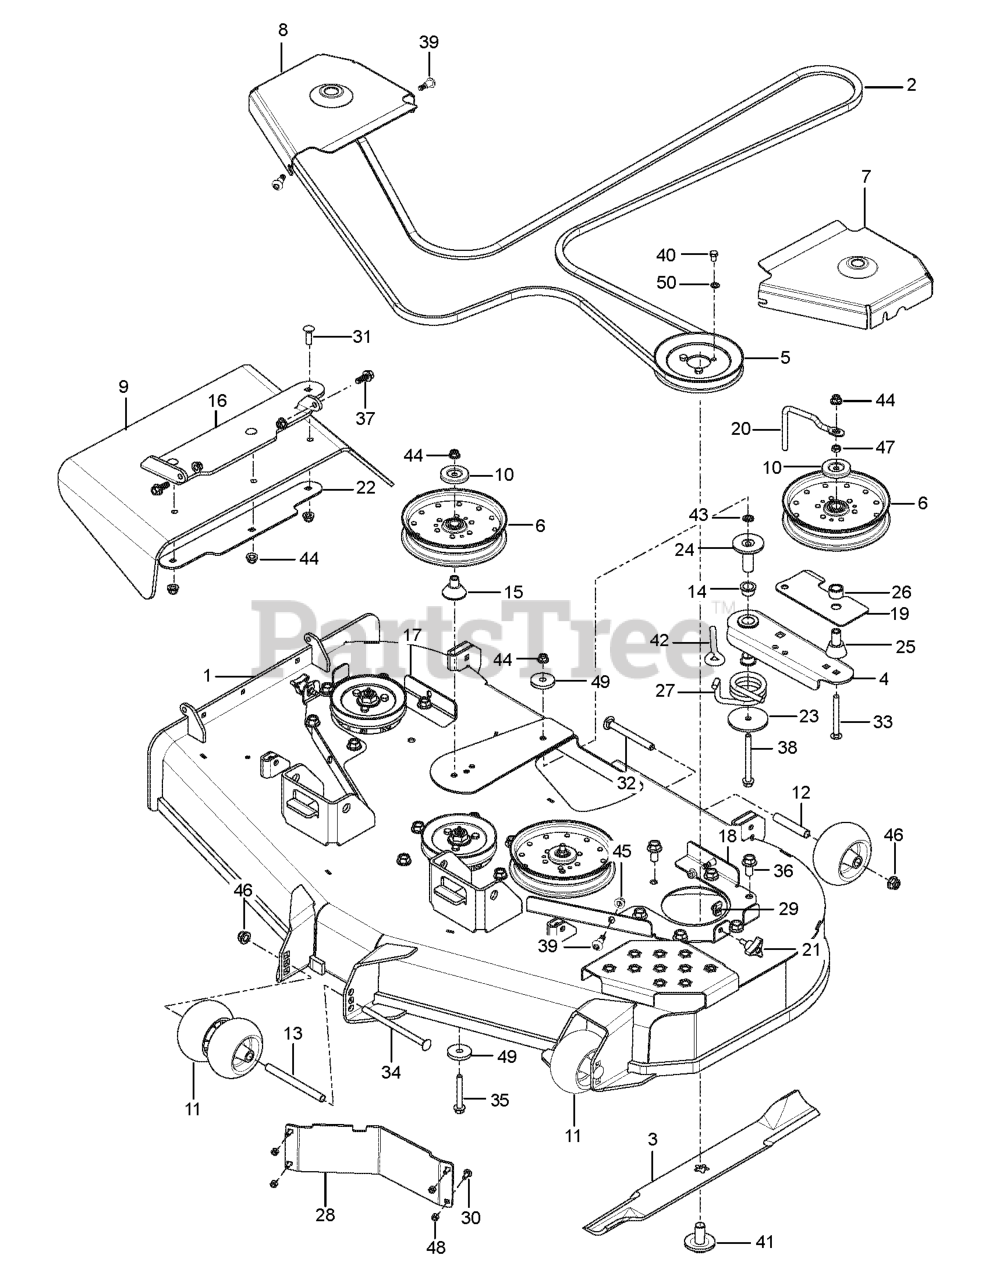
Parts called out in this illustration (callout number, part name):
1	DECK.SVC.W/DECALS.54".7GA.ORG
2	BELT.166".5V.SBR
3	BLADE, 19"
4	ARM.PNT.WLD.TENSIONR.IDLER.BLK
5	PULLEY - 5.93 OVER PINS
6	PULLEY - IDLER 7"
7	COVER.PULLEY.LH.PNT
8	COVER.PULLEY.RH.54"DECK.PNT
9	CHUTE.DISCHARGE
10	DUST SHIELD
11	ROLLER, GAUGE .635 BORN
12	TUBE, ROLLER AXLE
13	TUBE, ROLLER AXLE LONG
14	BEARING, FLANGE
15	BEARING, IDLER ARM
16	BRACKET.CHUTE.ORG
17	BRACKET.PULLEY.COVER.LH.PNT
18	BRACKET.PULLEY.COVER.RH.PNT
19	BELT.GUARD.LOWER.PLATE.PNT.431
20	KEEPER KEEPER., BELT
21	KNOB W/STUD
22	PLATE.BACKING.DISCHARGE.CHT.BK
23	PLATE.SPRING.RETAINER
24	SHAFT.MOUNT.ARM.IDLER
25	SPACER
26	SPACER.PULLEY.INTERMEDIATE
27	SPRING.TORSION.DECK.IDLER.TMSN
28	BAFFLE, DIVERTER 54"/60" LH
29	U-CLIP 5/16-18 NUT RETAINER
30	1/4-20X3/4 CARR BLT
31	BOLT.3/8-14X1.25
32	RHSNB 1/2-13 X 4.75 GR5 ZD
33	BOLT.RDHD SQNK 3/8-16 X 3-1/2
34	RHSNB 1/2-13 X 8 GR5 ZD
35	HHFS 3/8-16 X 2-3/4 GR5 ZD
36	HHFS 1/2-13 X 1 GR5 ZD
37	HHFS 3/8-16 X 1 GRD 5 ZD
38	HHFS 3/8-16 X 4 GR5 ZD
39	SCREW.SHLDR.3/8 X 1/2.5/16-18
40	HCS 5/16-18 X 1/2 GR 5 ZD
41	BLADE BOLT/WASHER
42	EYE BOLT, 3/8 X 4"
43	NUT 3/8 PALNUT RTNG BLK PHOS
44	NUT 3/8-16 HEX FLG NYLOC ZD
45	5/16-18 NYLOC FLANGE NUT
46	NUT, 1/2-13 HEX FLG NYLOC ZD
47	NUT 3/8-16 HEX JAM
48	NUT.1/4-20.HEX.NYLOC.ZD
49	SPINDLE WASHER
50	WASH 5/16 DISC SPRING ZD
